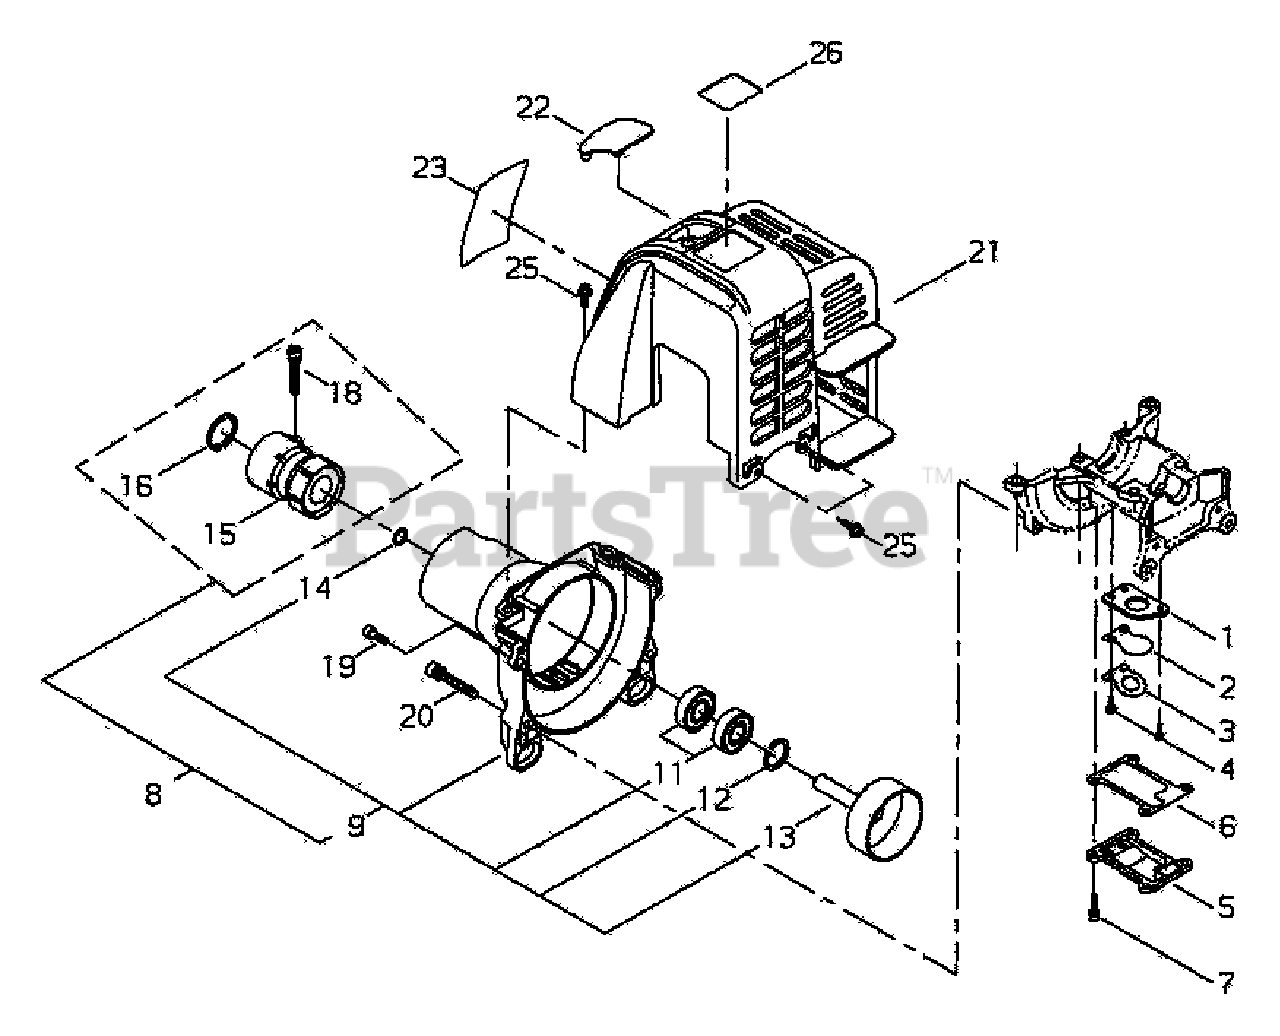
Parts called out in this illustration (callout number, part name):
1	PLATE, REED BACKING
2	VALVE, REED
3	STOP, REED VALVE
4	SCREW - 3X10
5	COVER, REED VALVE
6	GASKET, REED VALVE
7	SCREW - 4X12
8	FAN CASE ASSY
9	FAN CASE ASSY
11	BEARING, BALL - 6000
12	RING, RETAINING - 26
13	DRUM, CLUTCH
14	RING, RETAINING
15	CUSHION
16	RING, RETAINING - 40
18	SCREW - 5X22
19	SCREW - 5X16
20	SCREW - 5X45
21	COVER, ENGINE
22	COVER, SPARK PLUG
23	LABEL - C4
25	SCREW - 4X16
26	LABEL - MODEL
